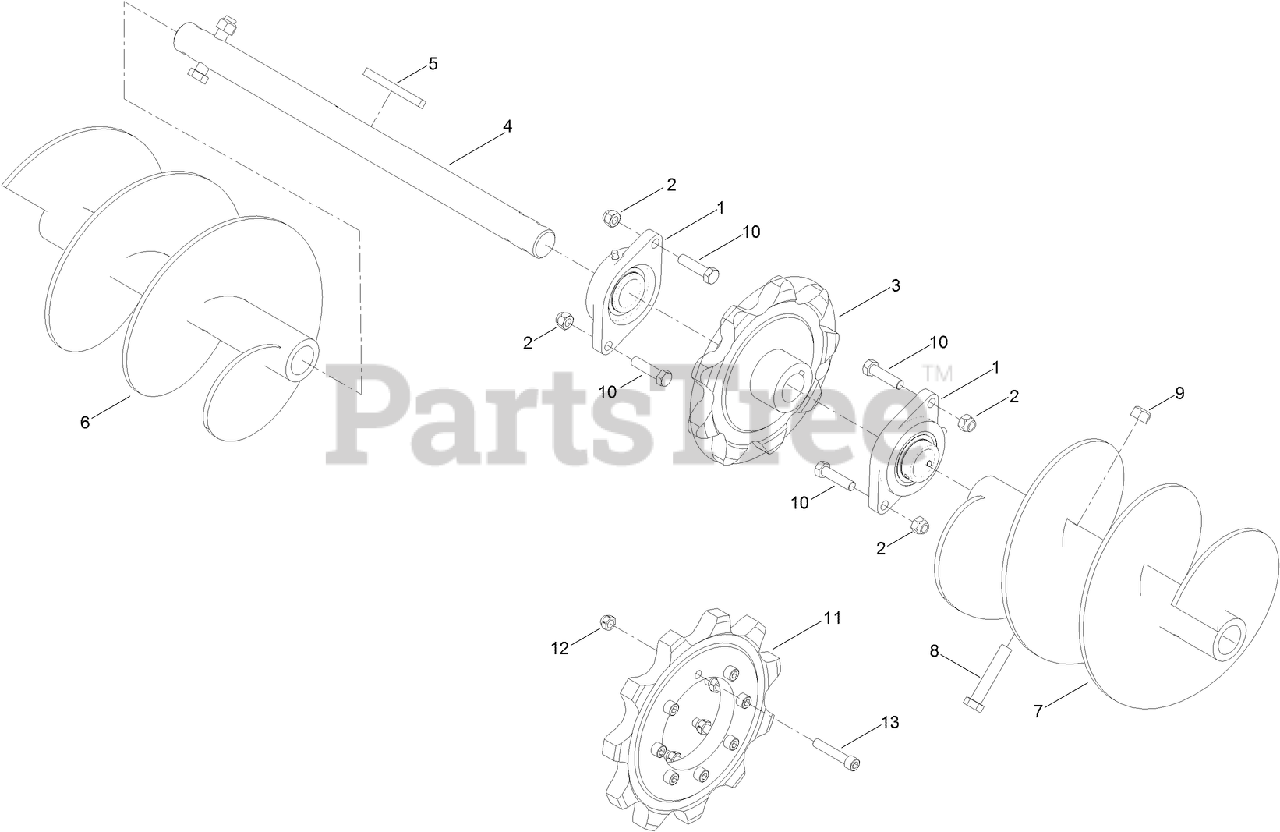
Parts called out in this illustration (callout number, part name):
1	BEARING-BALL, 2-BOLT FLANGE (2 IN)
2	NUT-LOCK, HEX
4	SHAFT-AUGER
5	KEY-SQUARE
9	NUT-LOCK
10	SCREW-HH
11	SPROCKET-SPLIT
12	NUT-HEX
13	SCREW-HSH
